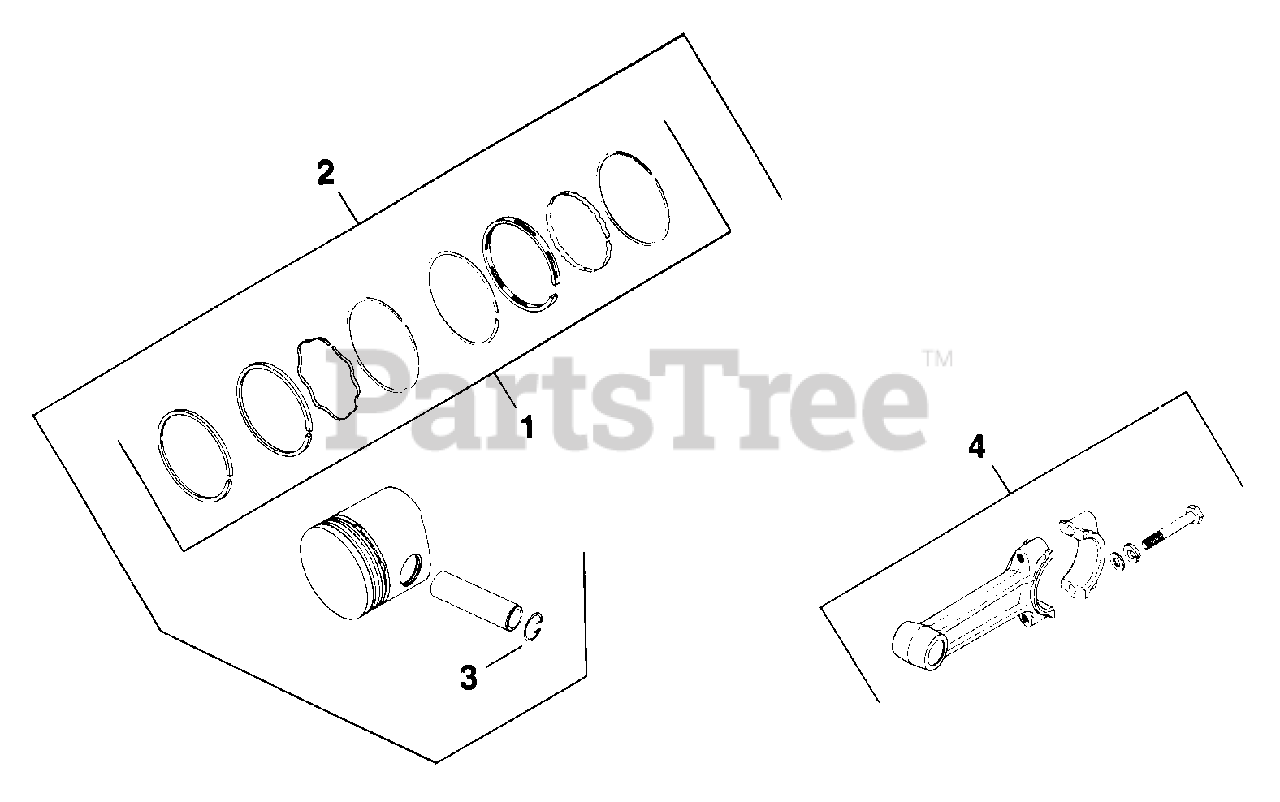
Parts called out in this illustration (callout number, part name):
1	RINGS STD.
1	RINGS .010
1	RINGS .020
1	RINGS .030
2	PISTON W/RING SET STD
2	KIT, PISTON W/RING SET .003 - (#DSC)
2	KIT, PISTON W/RING SET .010
2	KIT, PISTON W/RING SET .020
2	KIT, PISTON W/RING SET .030 - DISC.
3	RETAINER
4	ROD STD. - DISCONTINUED
4	ROD .010 - (#DSC)
